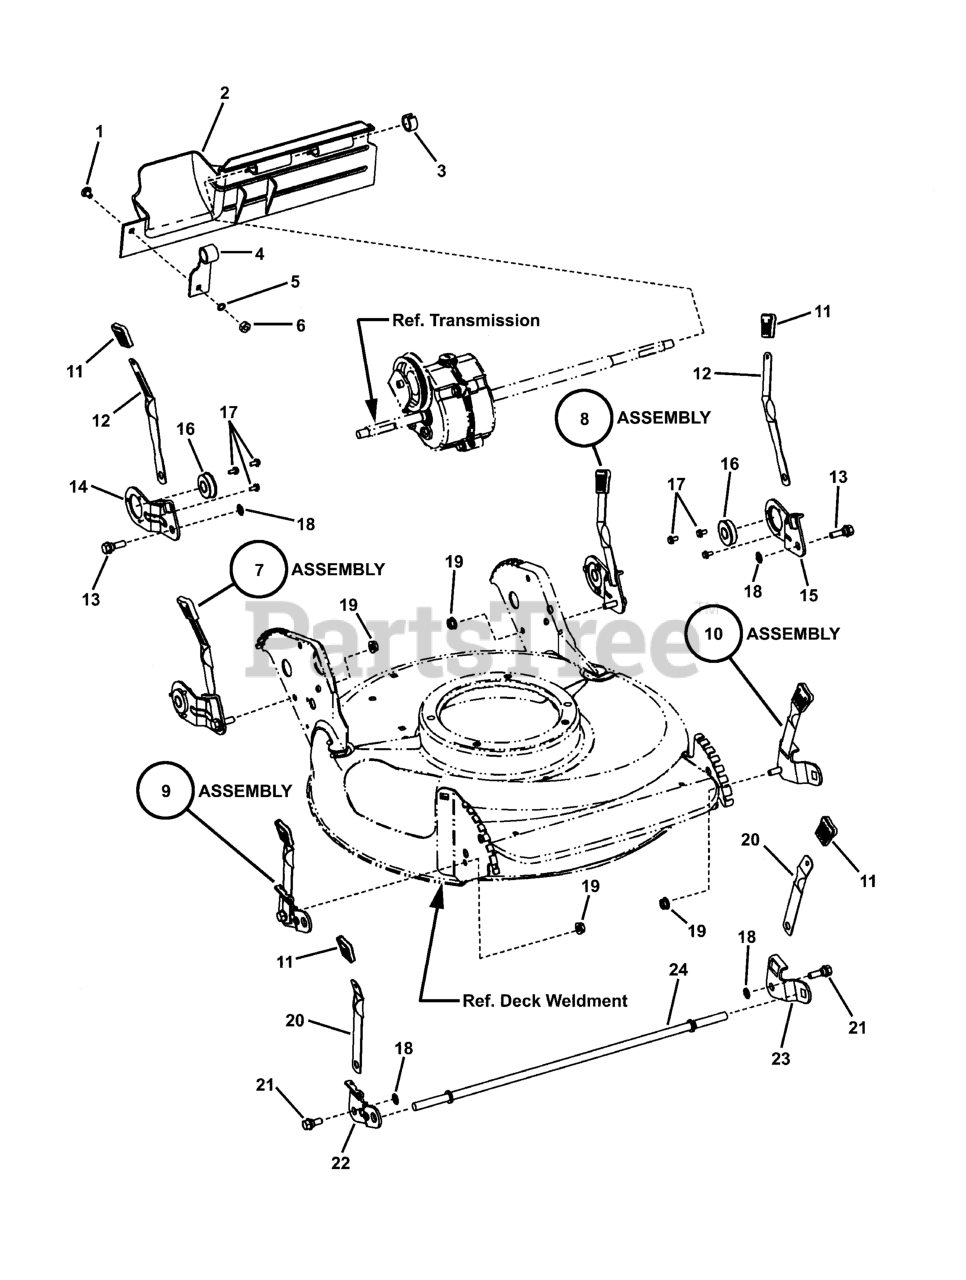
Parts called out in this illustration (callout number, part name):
1	BOLT, 1/4-20 x 1/2" Short Neck Carriage GR 5
2	FOOT GUARD, Rear
3	RING, Split (Black)
4	SUPPORT, Foot Guard
5	WASHER, 1/4" Internal Tooth Lock
6	NUT, 1/4-20 Hex, GR 5 or B
7	ASSY, Wheel Arm, Right Rear (S.P.)
8	ASSY, Wheel Arm Left Rear Long (S.P.)
9	ASSEMBLY, Right Wheel Arm
10	ASSEMBLY, Left Wheel Arm
11	GRIP, Height Latch
12	LATCH, Height Adjusting (long)
13	BOLT, 5/16-18 x 1" Hex Washer Face Shoulder
14	ARM, Wheel, Right Rear
15	ARM, Wheel, Left Rear
16	BEARING, 9/16" I.D.
17	SCREW, #10-32 x 3/8" Hex washer Self-Tap
18	RETAINER, 5/16" Bolt
19	NUT, 5/16-18 Hex Flange Lock, GR 5
20	LATCH, Height
21	BOLT, 5/16-18 x 3/4" Hex Washer Face Shoulder
22	WHEEL ARM, R.H. Front (Round Hole)
23	WHEEL ARM, L.H. Front (Square Hole)
24	AXLE, 21"
